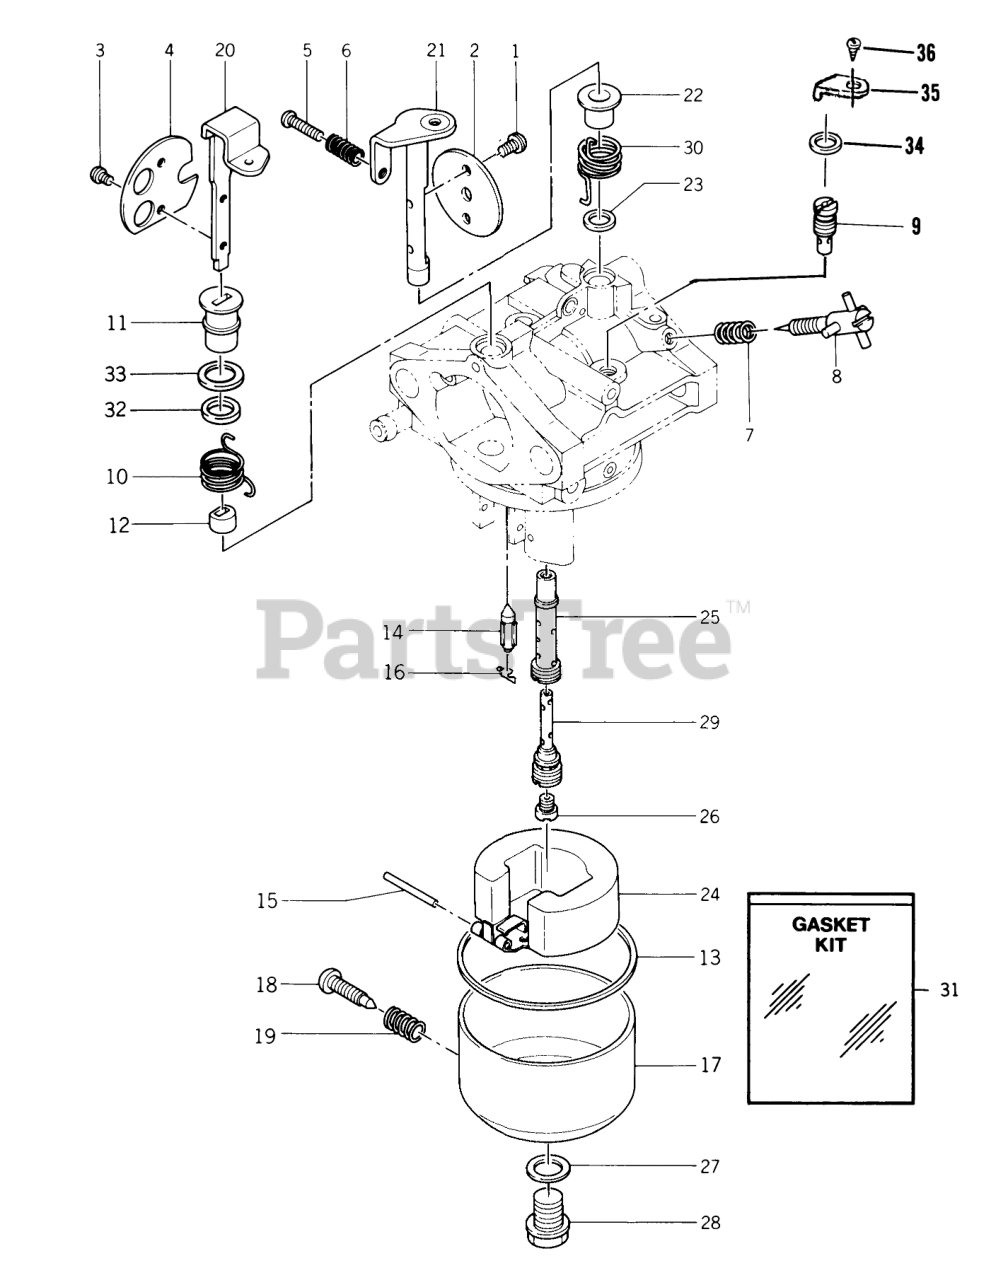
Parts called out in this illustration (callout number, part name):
1	SCREW-THROTTLE PLATE
2	VALVE THROTTLE
3	SCREW
4	VALVE CHOKE
5	SCREW
6	SPRING IDLE
7	SPRING
8	Adjuster Screw
9	Pilot Jet (#62.5)
10	SPRING
11	Collar
12	COLLAR
13	GASKET
14	Needle Valve Assy
15	PIN-FLOAT
17	Float Chamber Assy (includes items 18 & 19)
18	SCREW-DRAIN
19	SPRING
20	SHAFT-CHOKE
21	Shaft-Throttle
22	RING BUSHING
23	Seal
24	FLOAT
25	NOZZLE-MAIN
26	JET MAIN
27	GASKET
29	HOLDER-MAIN JET
30	Spring
31	Carburetor Gasket Set
32	Washer
34	O-RING
35	PLATE
36	Screw
